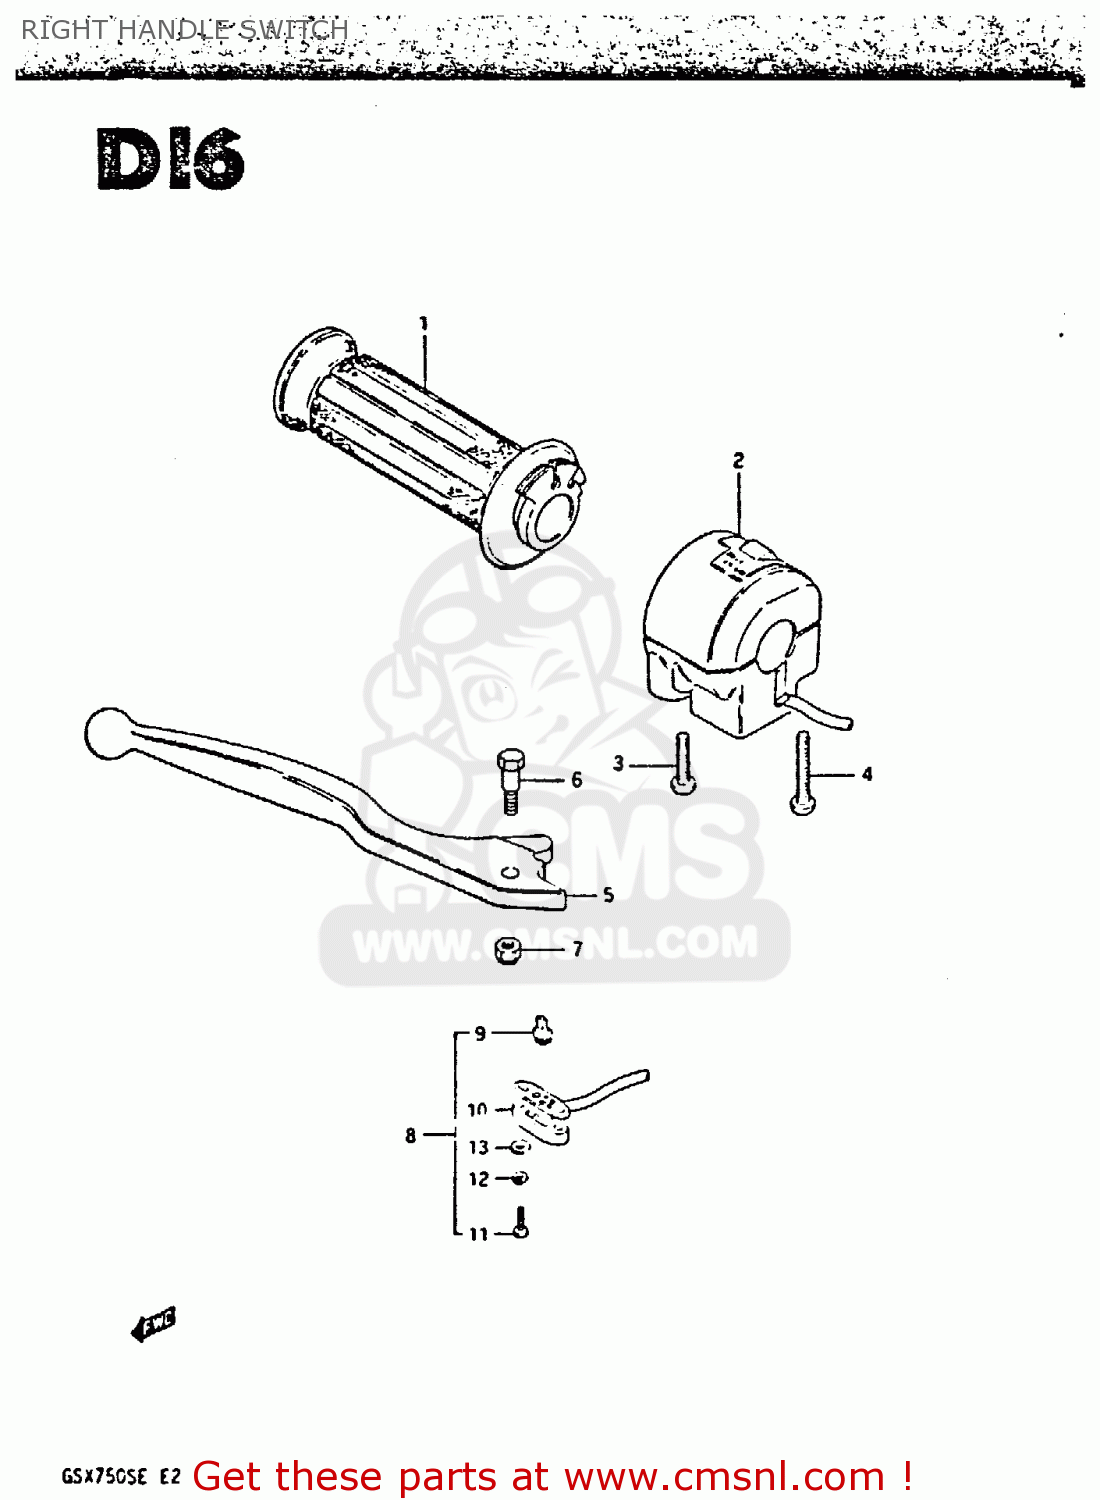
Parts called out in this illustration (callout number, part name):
1	GRIP,THROTTLE
2	SWITCH ASSY, HANDLE RH
3	SCREW
4	SCREW
5	LEVER,BRAKE
6	BOLT,LEVER
7	NUT
8	SWITCH ASSEMBLY
9	CONTACT,SWITCH
10	COVER,FR BK TERMINAL BASE
11	SCREW
12	LOCK WASHER
13	WASHER
